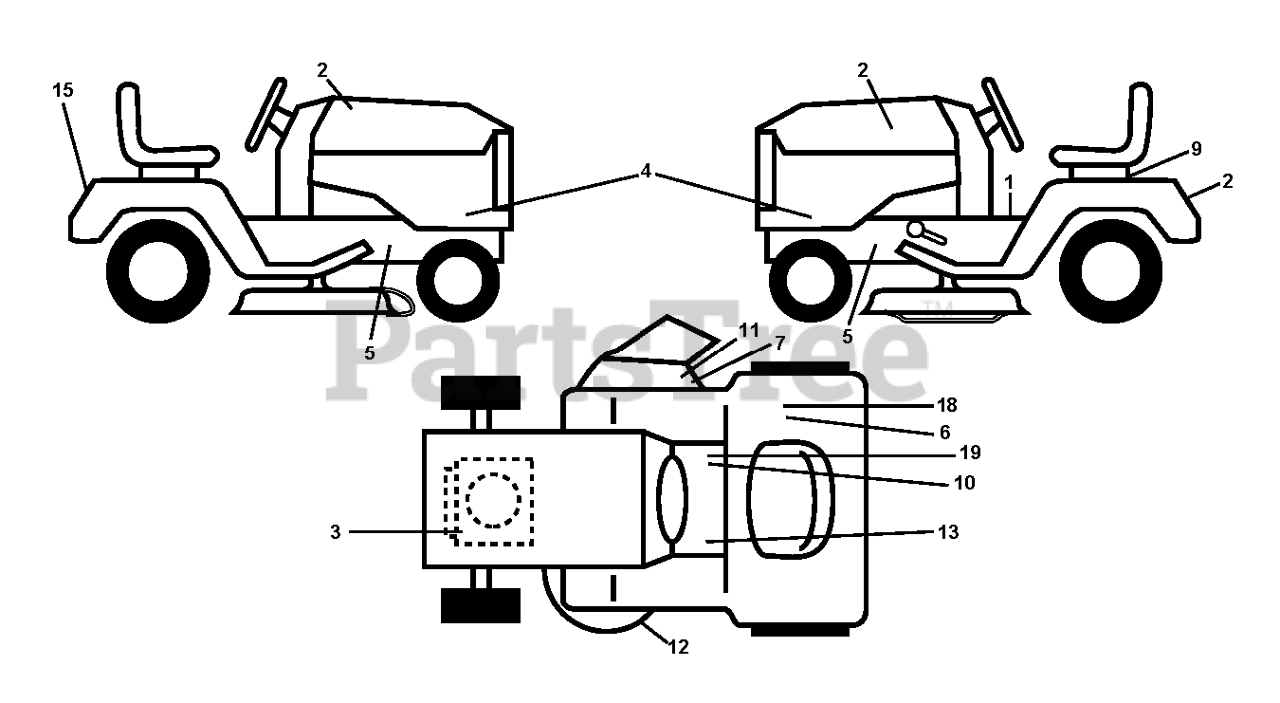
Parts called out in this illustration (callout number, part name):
1	LABEL
2	DECAL.HOOD.LOGO.ORANGE.HUSQVAR
3	DECAL
6	DECAL 80 DBA
7	DECAL, DEFLECT WARNING
9	DECAL BTRY SYMBOLS
10	DECAL PARK BRAKE
11	DECAL.INTERNATIONL.CUTFINGER
12	DECAL.V-BELT.SCHEMATIC.36/38/9
13	DECAL
15	DECAL.HOOD.NAMELOGO.HUSQ
18	DECAL
19	DECAL
